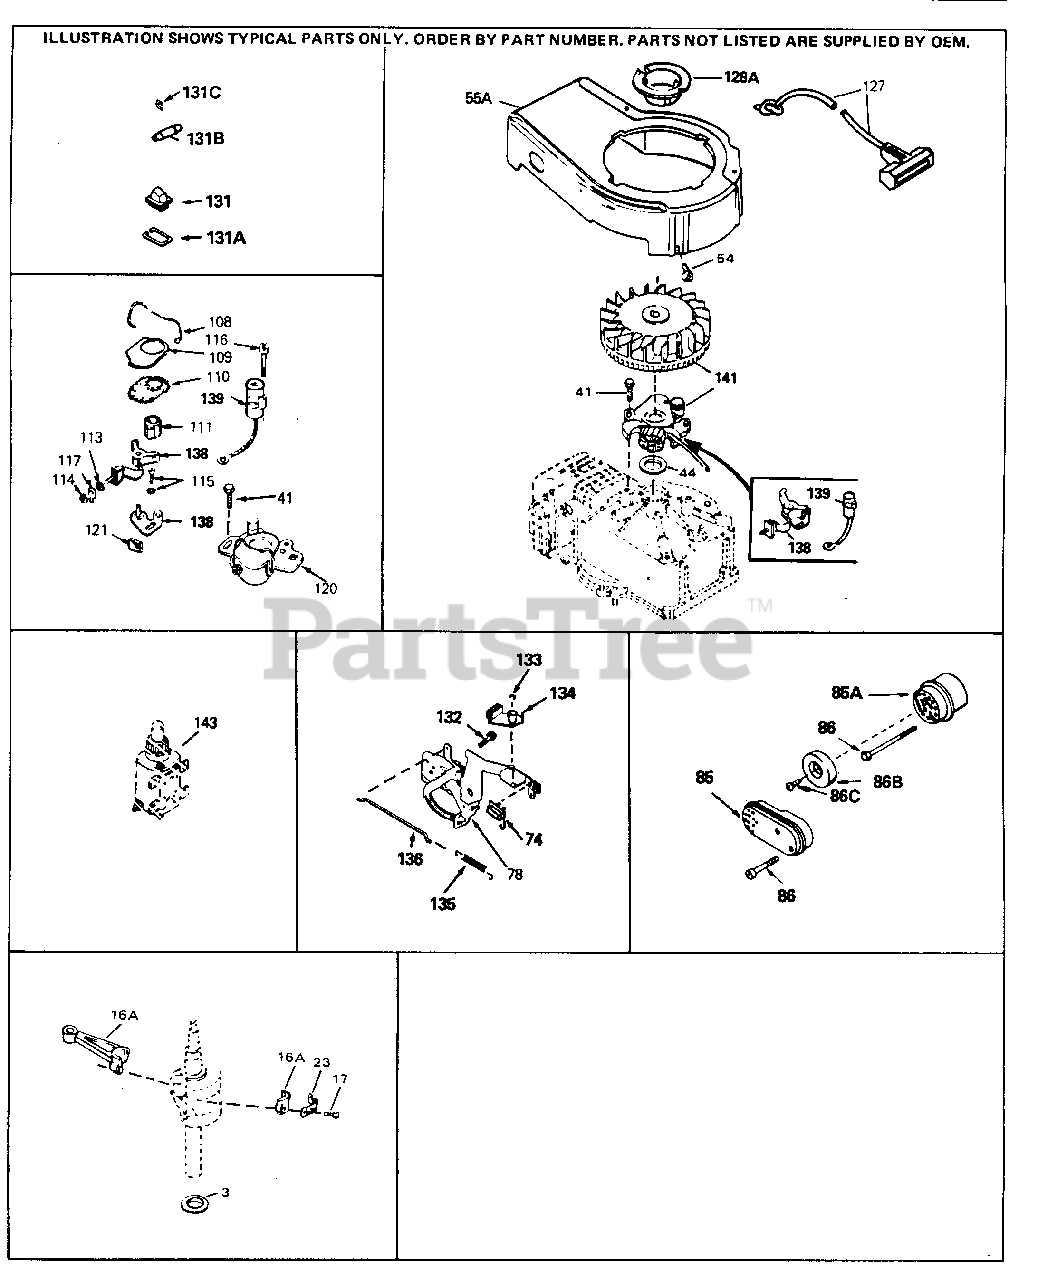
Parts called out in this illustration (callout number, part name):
3	Washer, Thrust
16A	Rod Assy., Connecting (Incl. 17)
17	Bolt, Connecting rod
23	Plate, Lock Used on early production with No. 32610 connecting rod bolt. D onot use with No. 32610A locking type bolt.
41	Screw, 1/4-20 x 5/8"
54	Screw, 1/4-20 x 5/8"
55A	Housing, Blower
74	Terminal Assy. (Use as required)
127	Rope Assy., Starter
128A	Cup Early production only, not w/650 791
138	Breaker Points (also available in Pac kaged Part #740037B)
139	Condenser (also available in Packaged Part #740037B)
141	Magneto (w/ring gear) NOTE: The comp lete magneto is not available as an a ssembly. The magneto number is shown for reference purposes only. Order componentparts individually, as shown in parts list. (Refer to Division 5, Section B, page 30 for br
143	Electric Starter Kit Supplied by OEM
